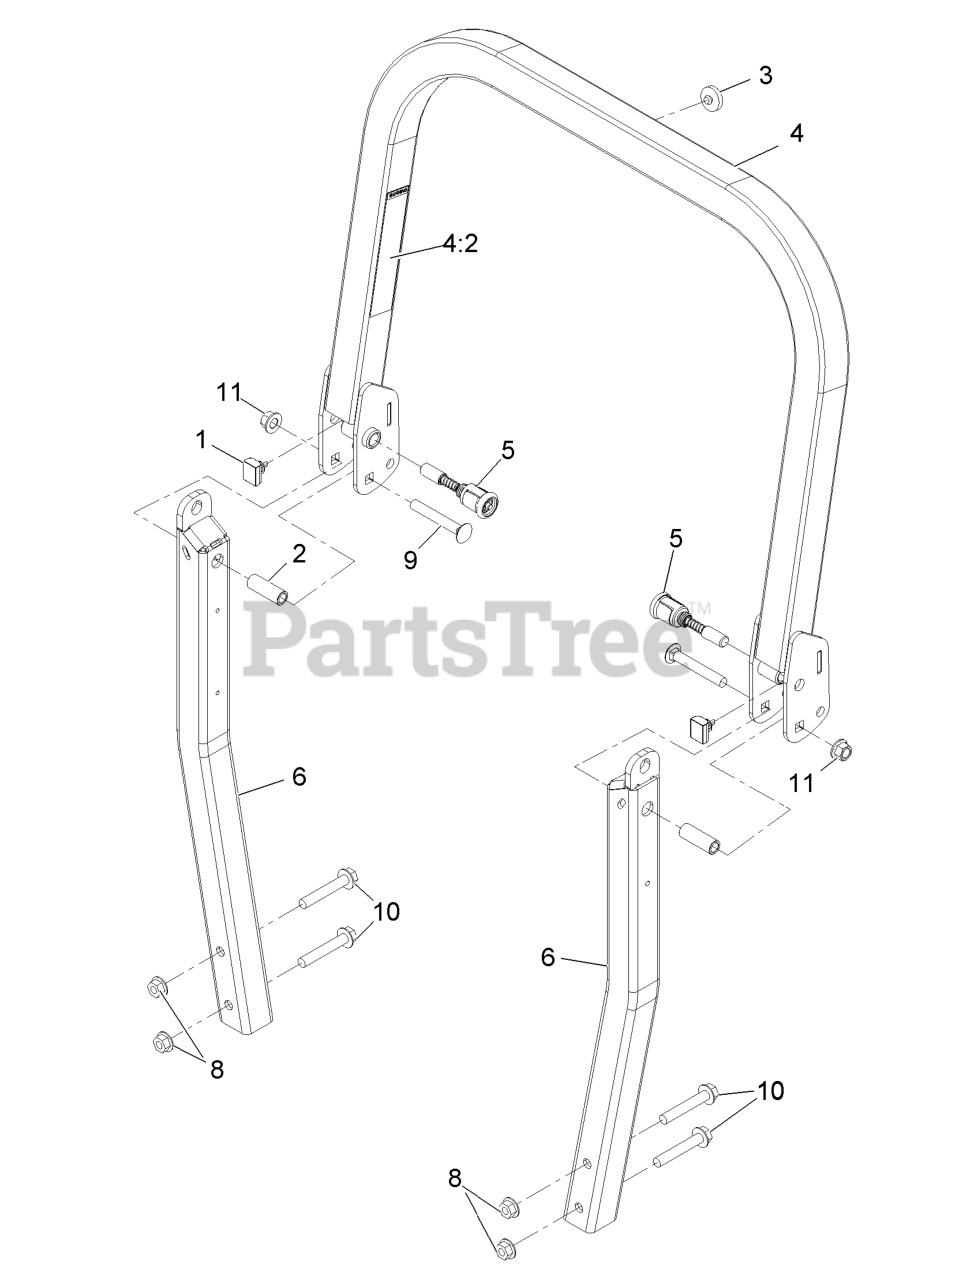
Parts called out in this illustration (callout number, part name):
1	BUMPER-ROPS
3	BUMPER-PUSH-IN, RUBBER
4	UPPER ROPS ASM
4:2	DECAL-WARNING, FOLDING RO
5	PIN-SPRING
6	NUT-HHF
9	SCREW-CARR
10	SCREW-HF
11	Nut-Lock 1/2-13
